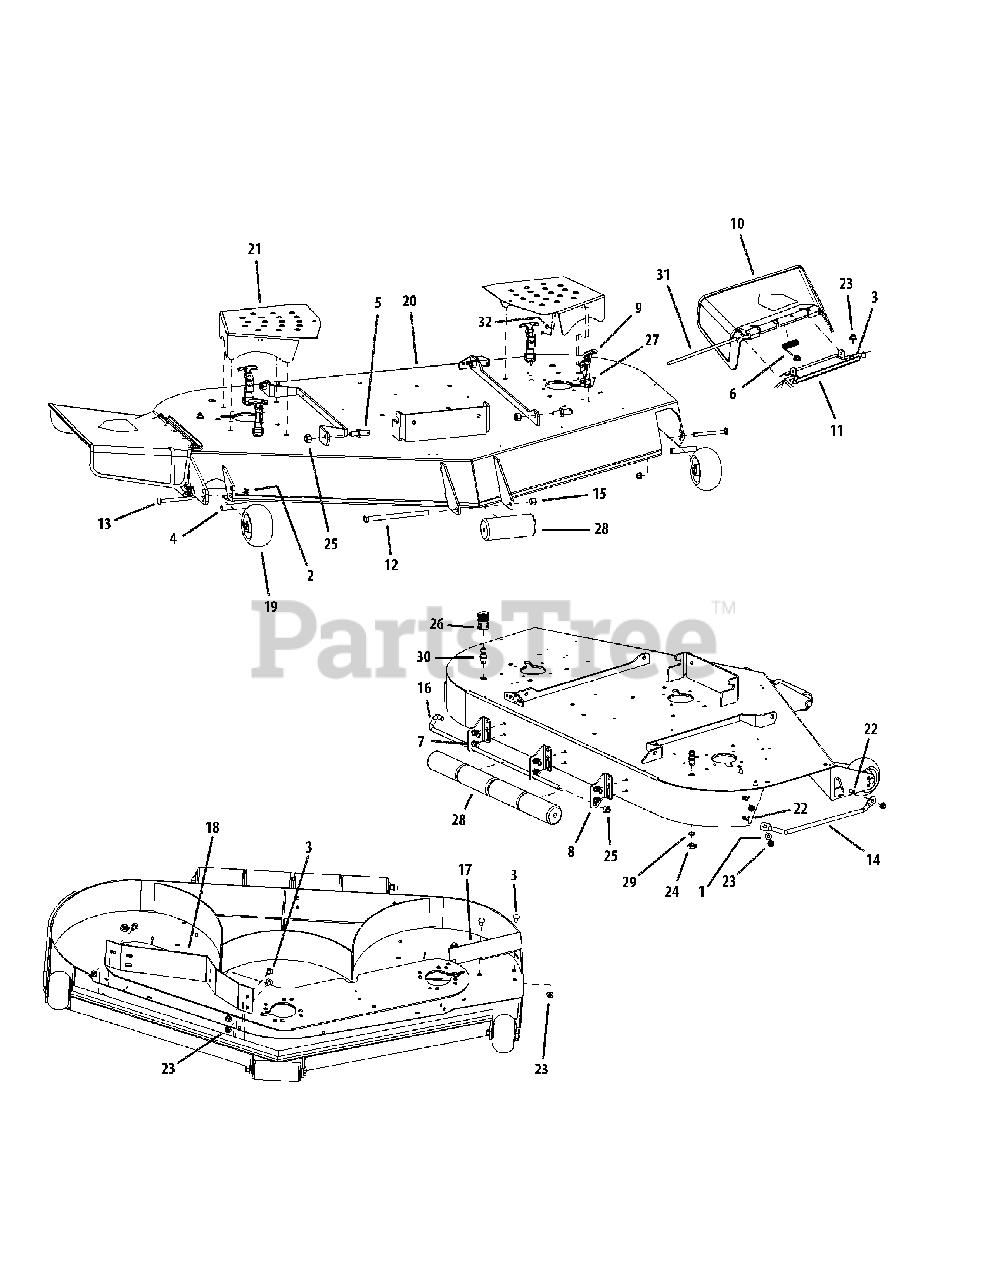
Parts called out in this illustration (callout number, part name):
1	Washer, 3/8
2	Flange Lock Hex Nut, 3/8-16
3	Carriage Bolt, 3/8-16 x .75 Lg.
4	Spacer, .390 x .620 x 3.04
5	Pin, 5/8 Dia. x 1.2 Lg.
6	Spring Torsion, 0.639 ID x 2.16 LG
7	Hex Index Washer Screw, 3/8-16,
9	T-Handle Latch Draw
10	Chute Deflector
11	Chute Deflector Bracket
12	Hex Cap Screw, 1/2-20 x 7.50
13	Carriage Bolt, 3/8-16 x 4.00
14	Finger Guard
15	Lock Nut, Nylon Insert, 1/2-20
16	J-Hook w/ Threaded Roller
18	Baffle, 60" Adjustment
19	Complete Wheel, 5.00 Dia.
20	60" Deck Assembly
21	Deck Belt Cover
22	Carriage Bolt, 3/8-16 x 1.00
23	Lock Nut, Nylon Insert, 3/8-16
24	Hex Nut, M16-1.5
25	Lock Nut, Nylon Insert, 1/2-13
26	Water Nozzle Adaptor
27	Phillips Head Screw, 10-32
28	Front Roller
29	Lock Washer, 17 x 23.8 x 1.95
30	Deck Water Nozzle
31	Chute Deflector Rod
32	Lock Nut, Nylon Insert, 10-32
